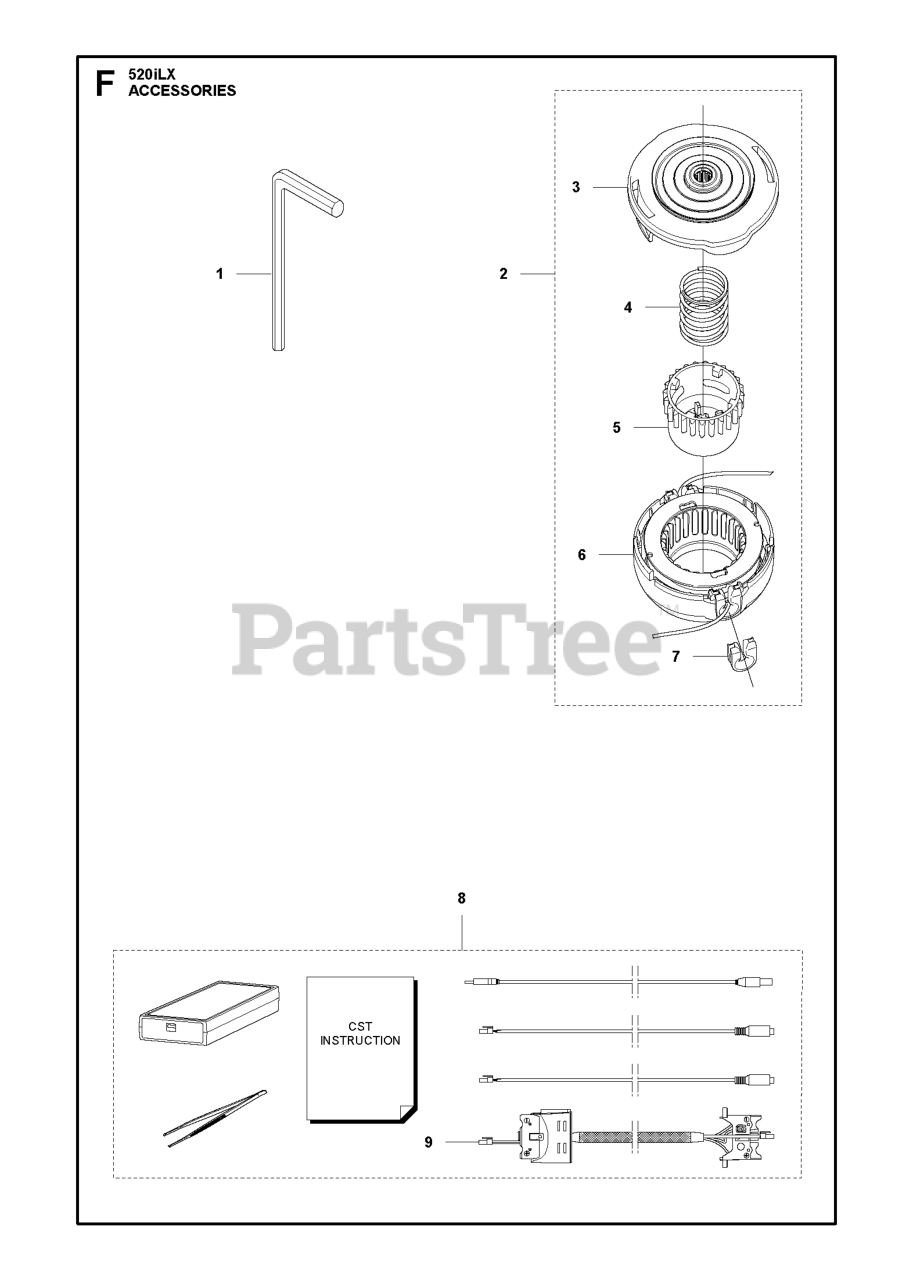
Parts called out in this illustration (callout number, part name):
2	TRIMMER HEAD T25B M10
3	HOUSING ASSY TRIMMERHEAD T25B
8	DIAGNOSTIC TOOL KIT
9	WIRING ASSY
